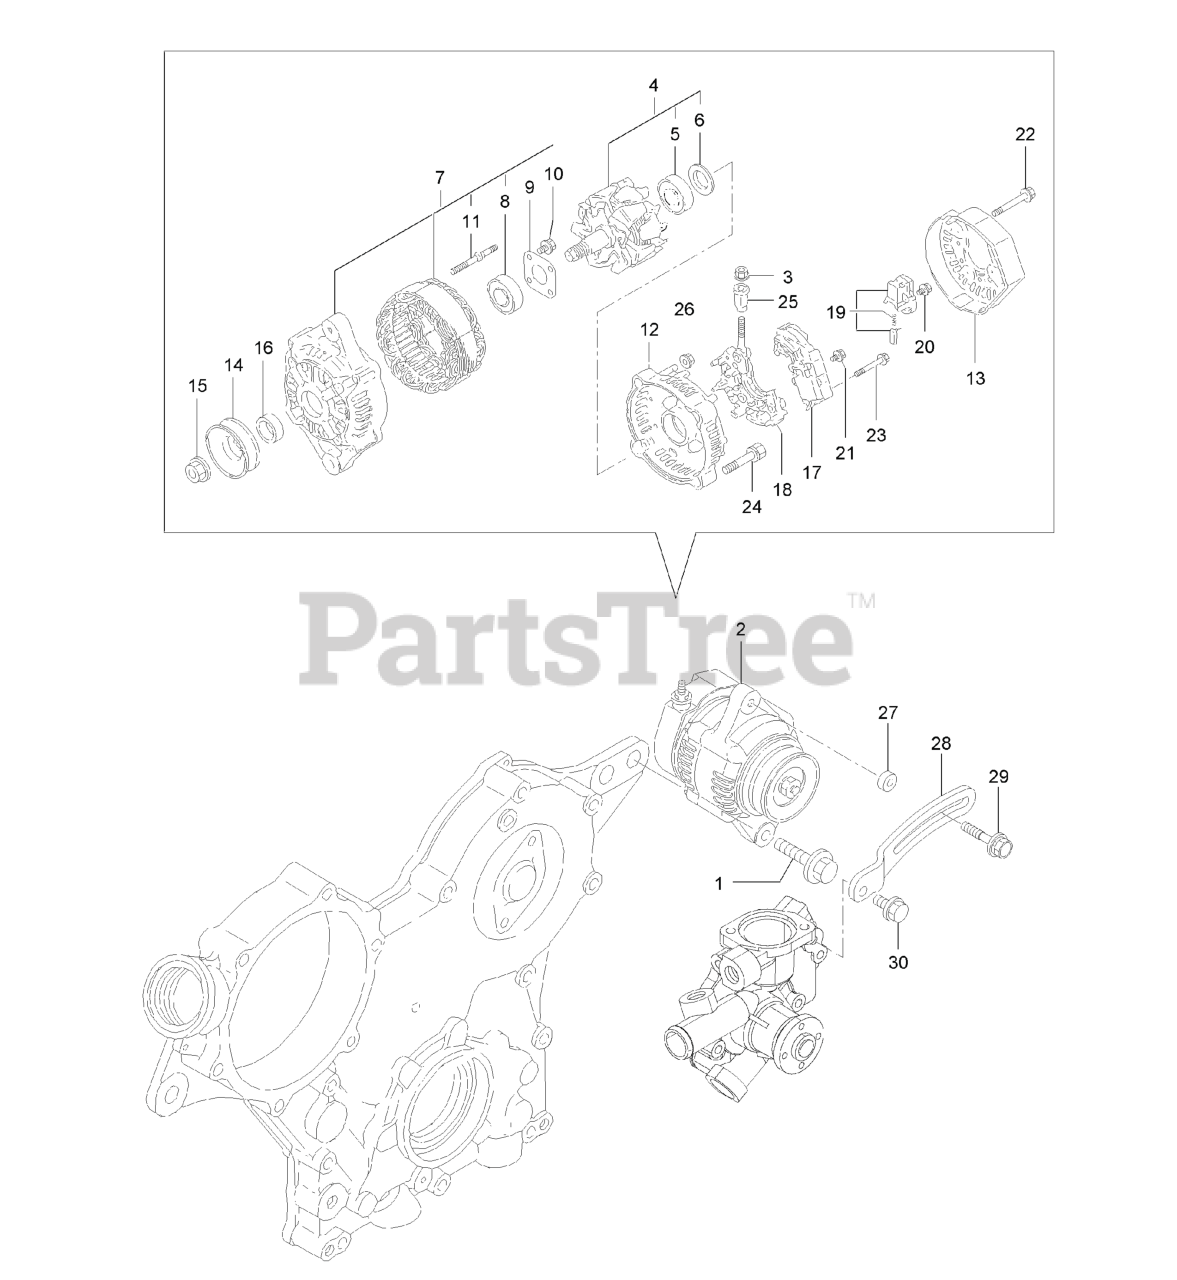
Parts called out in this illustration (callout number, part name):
2	ALTERNATOR
4	Rotor ASM
5	BEARING-BALL
7	FRAME ASM
8	BEARING-BALL
9	Plate-Retainer
17	REGULATOR ASM
25	Bushing-Insulation
28	ADJUSTER-BELT
